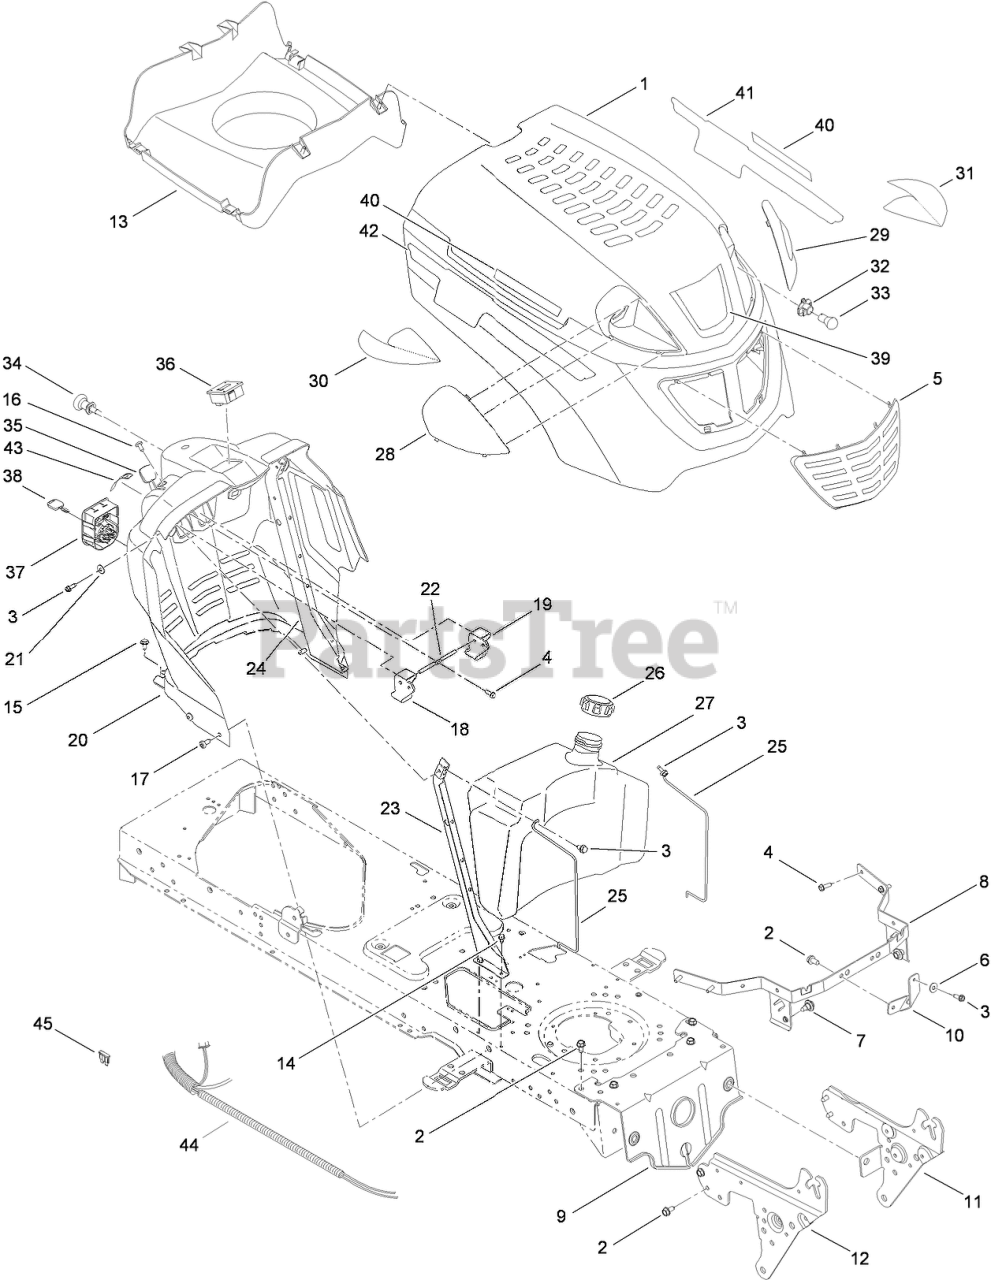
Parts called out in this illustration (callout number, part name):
2	SCREW-TAP
3	SCREW-TAP
4	SCREW-TAP
6	WASHER-FLAT
7	BOLT-SHOULDER, TAP
8	BRACKET-PIVOT
9	BRACKET-PIVOT
10	BRACKET-SUPPORT, HOOD
11	BRACKET-SUPPORT, PIVOT (LH)
12	BRACKET-SUPPORT, PIVOT (RH)
13	PLENUM-HOOD
14	SCREW-HWHTF
15	SCREW-TAP
16	SCREW-TAP
17	SCREW-TAP
18	LEVER-CRUISE
19	LEVER-BRAKE
20	COVER-LIFT, LEVER
21	WASHER-SPRING
22	ROD-LEVER, BENT
23	SUPPORT-DASH, PLATE (RH)
24	SUPPORT-DASH, PLATE (LH)
25	ROD-SUPPORT
26	CAP-FUEL
27	TANK-FUEL, 3 GAL
28	LENS-RH
29	LENS-LH
30	REFLECTOR-RH
31	REFLECTOR-LH
32	SOCKET-HEADLIGHT
33	LAMP-12V, MINIATURE
34	CABLE CONTROL ASM (W/CHOKE KNOB)
35	CABLE-THROTTLE
36	METER-HOUR
37	MODULE-SWITCH, IGNITION
38	KEY-IGNITION
39	DECAL-HOOD
41	DECAL-HOOD, LEFT SIDE
42	DECAL-HOOD, RIGHT SIDE
43	DECAL-THROTTLE
44	Harness-Wire
45	FUSE-20 AMP
